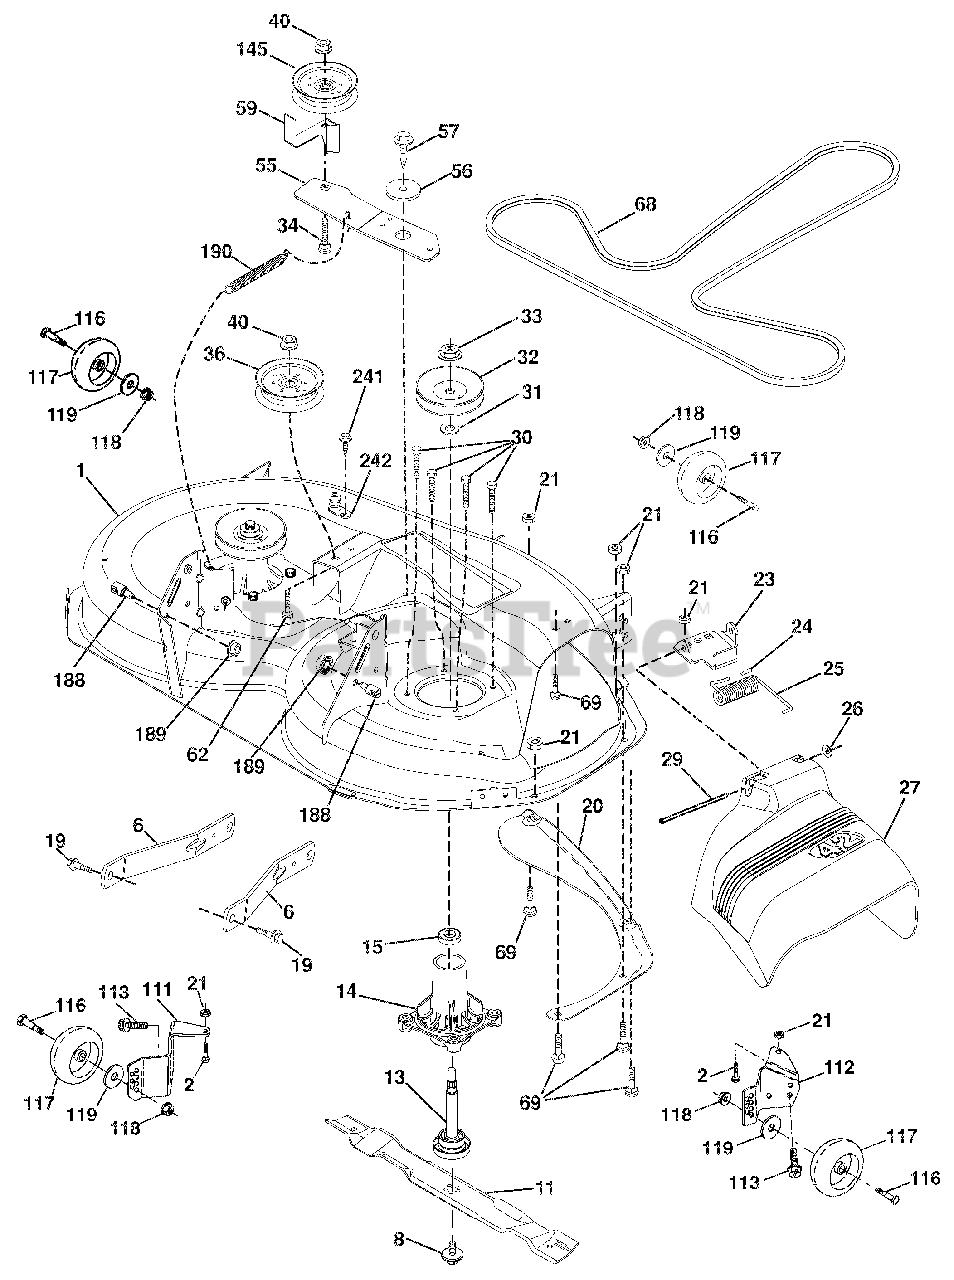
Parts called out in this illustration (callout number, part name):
1	MOWER HOUSING
6	ARM.SUSPENSION.MOWER.REAR.LD
8	BOLT/WASHER ASM.7/16-20.UNF
11	BLADE.MOWER.42"HI LIFT PREMIUM
13	SHAFT ASM.MNDRL.N/GREASEABLE38
14	HOUSING.MANDREL.4PT.SERVICE
15	BEARING.BALL.MANDREL
19	BOLT.SHOULDER
20	BAFFLE.VORTEX.42.STD/HEAVY DTY
21	Nut, Hex, Crownlock 5/16-18
23	BRACKET.DEFLECTOR.38/42"2005
24	CAP.SLEEVE..80X.112.BLK.MOWER
25	SPRING.TORSION.DFL.38/42/46.GR
26	NUT.PUSH.PHOS.& OIL
27	SHIELD.DEFLECTOR.
29	ROD.HINGE.42/46"
30	SCREW.THD ROLL.DOD PT.HEX
31	WASHER.SPACER.MANDREL
32	MANDREL.PULLEYS.42,44,50
33	NUT.FLANGE.LOCK.TOP
34	BOLT.CARR.SH.3/8-16X1-1/2.GR5
36	PULLEY.IDLER.4.50.RAW
40	Nut, Hex, Flangelock 3/8-16
55	IDLER.ARM
56	SPACER.RETAINER
57	SCREW.3/8-16X1.SMGML.TAP/R.BLK
59	GUARD.TUV.IDLER
62	BOLT.RD.HD.SQ.NK.3/8-16UNC X 2
68	V-Belt, 42" Mower
69	BOLT.RDHD.SQNK.5/16-18 X 5/8
111	BRACKET WHEEL GAUGE LH
112	BRACKET WHEEL GAUGE RH
113	BOLT.5/16-18HEX.WHS.HD.LCKSERR
116	BOLD SHLD "A" 2.41 "B" 1.66
117	WHEEL.GAGE.HALF.SPOKED
118	Nut, Hex, Flangelock 3/8-16
119	Washer 3/8 x 7/8 x 14 Ga.
145	PULLEY.IDLER 48"PRIMARY
188	STUD.FASTNER.W/'D'ANTI-ROTATIO
189	Nut, Lock Hex Flange 5/16-18 u
242	PORT WASHOUT
